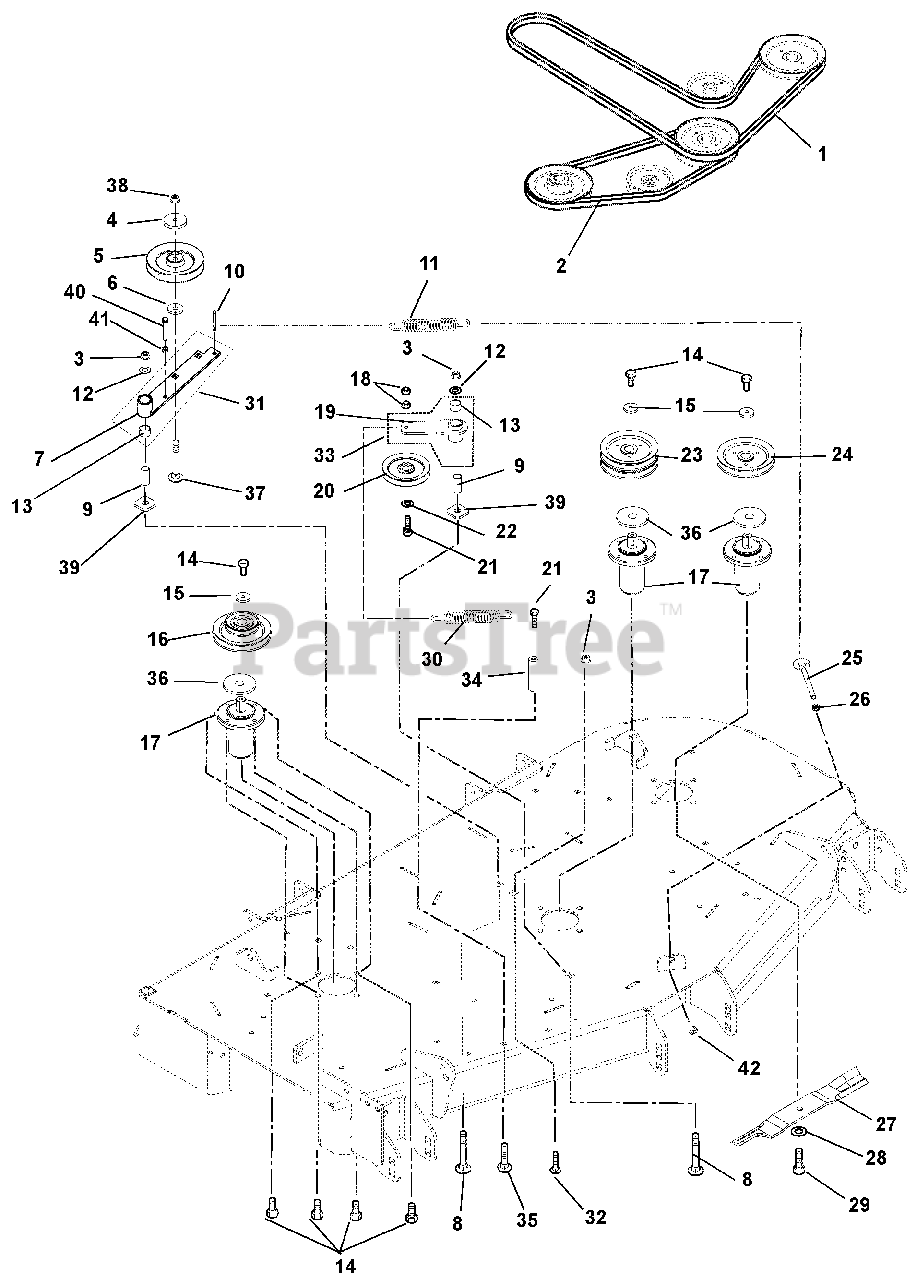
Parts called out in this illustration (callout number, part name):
1	Belt, 184.4" Long, PTO Drive Hex (992215)
2	V-Belt, 63" Long Cog B-Section (992215)
3	Nut, .50-13 Nyloc Flange
4	Cap, Idler Bearing Sealing
5	Sheave, .50" ID x 6.00" OD V-Idler
6	Bushing, Spacer .502 x .997 x .50
7	Weldment, Idler Arm
8	Bolt, Round Head Square Neck .50-13 x 3.50 Grade 5
9	Bushing, Spacer .505/.500 x .999/.996 x 2.05/2.03
10	Bolt, Shoulder EP .38-16 x .30 Hex
11	Spring, Extension (Deck Idler)
12	Washer, Flat Steel .563 x 1.38 x .109
13	Bushing, 1.00 x 1.125 x 1.936
14	Bolt, Hex .38-16 x 1.00
15	Washer, Flat Steel .406 x 1.50 x .245
16	Sheave, Double, 1" ID x 6.75" x 4.25" OD (992215)
17	Spindle Assembly (992216)
18	Nut, Locking Center .38-16
19	Weldment, Idler Arm
20	Assembly, V-Idler 5.00 OD
21	Bolt, Hex .38-16 x 2.25
22	Washer, Flat Steel .406 x .812 x .065
23	Sheave, Double 1" ID x 6.75" OD (992215)
24	Sheave, Single 1" ID x 6.75" OD (992215)
25	Bolt, .38-16 x 5.50 .62 Diameter Eye
26	Nut, Hex, Jam .375-16
27	Blade, Mower (20.50") (992215)
28	Washer, Belleville .63 x 1.625 x.14
29	Bolt, Hex .62-18 x 1.75 Grade 8
30	Spring, Extension
31	Assembly, PTO Idler Pivot Arm (Includes item # 7 and item # 13)
32	Bolt, Round Head Square Neck .50-13 x 1.5, Full Thread, Grade 5
33	Assembly, Idler Arm (Includes item # 13 and item # 19 )
34	Nut, Coupling .375-16 x 1.75
35	Bolt, Round Head Square Neck .38-16 x 1.00
36	Retainer, Grease
37	Bolt, Round Head Square Neck .50-13 x 3.00 Grade 5
38	Nut .50-13 Nyloc Flange
39	Washer, Flat .640 x 1.75 x .250
40	Bolt, Hex .38-16 x 2.75
41	Nut, Hex .38-16
42	Nut, Locking Center Jam .375-16
